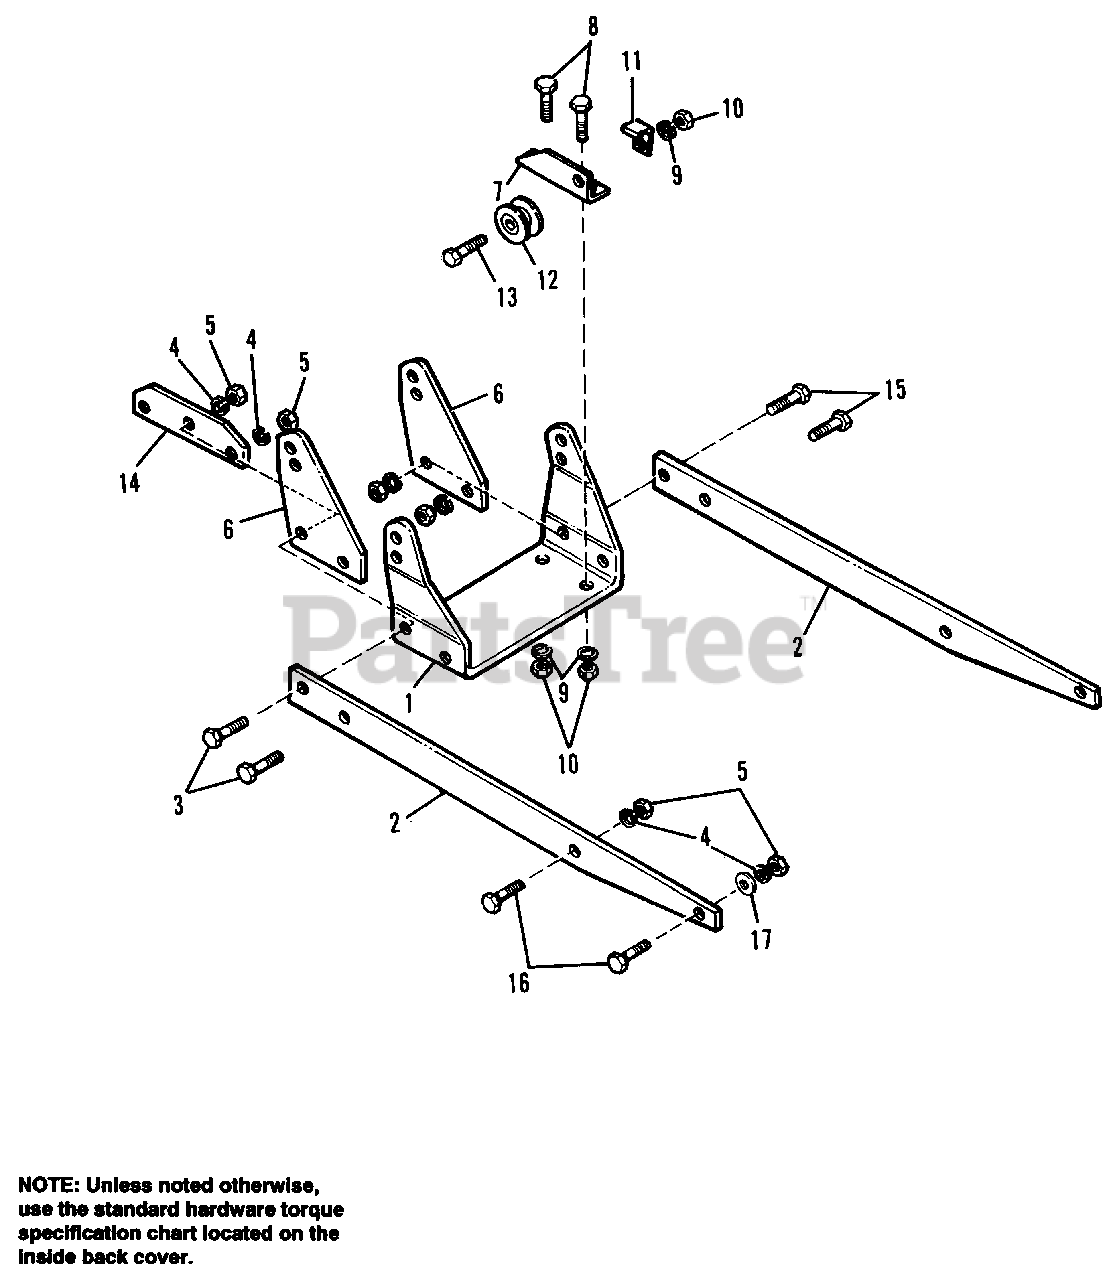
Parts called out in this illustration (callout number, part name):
1	BRACKET, Pivot
2	FLATBAR, Attaching
3	CAPSCREW, Hex Hd., 7/16-14 x 1-3/4
4	LOCKWASHER, 7/16
5	NUT, Hex, 7/16-14
6	BRACKET, Support, Pivot
7	SUPPORT, Idler
8	CAPSCREW, Hex Hd., 3/8-16 X 1
9	LOCKWASHER, 3/8
10	NUT, Hex, 3/8-16
11	GUIDE, Belt
12	PULLEY, Idler
13	CAPSCREW, Hex Hd., 3/8-16 x 1-3/4
14	BRACKET, Lift Rod
15	CAPSCREW, Hex Hd., 7/16-14 x 1-1/2
16	CAPSCREW, Hex Hd., 7/16-18 x 1-1/4
17	WASHER, Plain, 7/16
